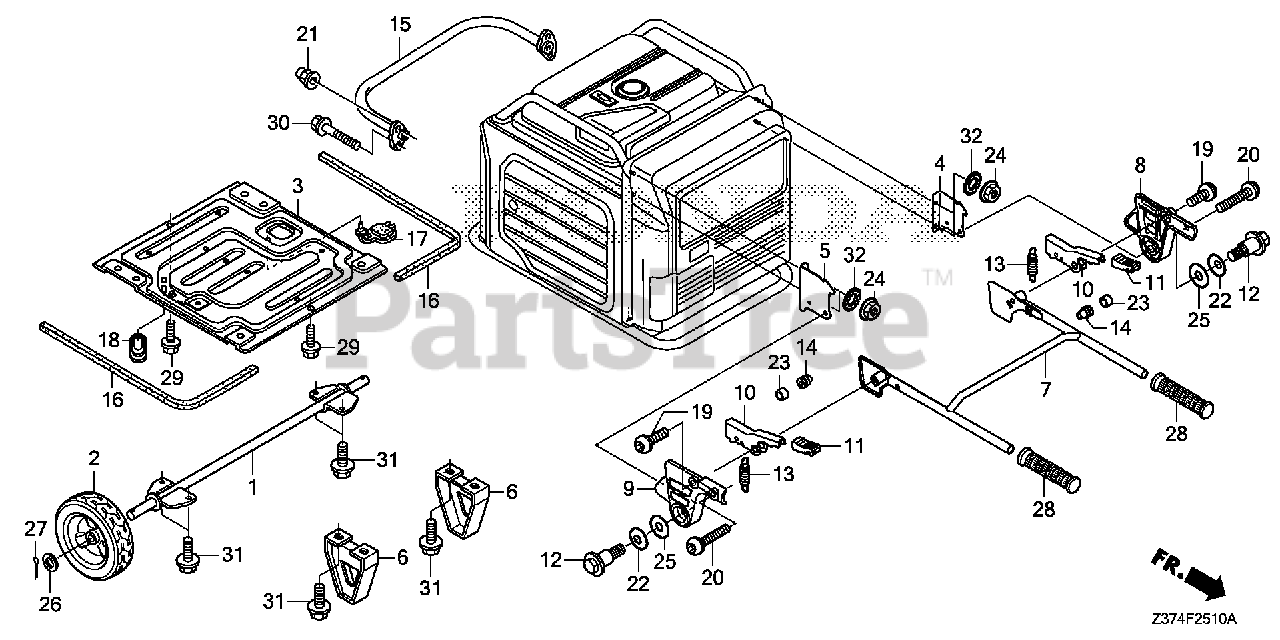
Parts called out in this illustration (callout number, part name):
1	SHAFT, WHEEL
2	WHEEL (254X75)
3	PLATE (LOWER)
4	BRACKET, R. HANDLE
4	BRACKET, R. HANDLE (NOT AVAILABLE)
5	BRACKET, L. HANDLE
5	BRACKET, L. HANDLE (NOT AVAILABLE)
6	STAND *NH105* (MAT BLACK)
7	PIPE, HANDLE *NH105* (MAT BLACK)
7	PIPE, HANDLE *NH105* (COO) (MAT BLACK)
8	HOLDER, R. HANDLE
9	HOLDER, L. HANDLE
10	LEVER, HANDLE
11	RUBBER, GRIP
12	BOLT, HANDLE HOLDER
13	SPRING, HANDLE LEVER
14	RUBBER, STOPPER
15	PIPE, RR. *NH105* (MAT BLACK)
16	SEAL (8X8X705)
17	PLUG, OIL DRAIN
19	BOLT, SOCKET (8X22)
20	BOLT, SOCKET (8X45)
21	NUT, OPEN STAY (6MM)
22	WASHER, SPRING
23	COLLAR, HANDLE
24	NUT, FLANGE (8MM)
25	WASHER, PLAIN (12MM)
26	WASHER, PLAIN (20MM)
27	PIN, SPLIT (4.0X28)
27	PIN, COTTER (4.0X30)
28	GRIP D, R. HANDLE (BOTH SIDES)
29	BOLT, FLANGE (6X16)
30	BOLT, FLANGE (6X30)
31	BOLT, FLANGE (8X20)
32	WASHER, LOCK (8MM)
